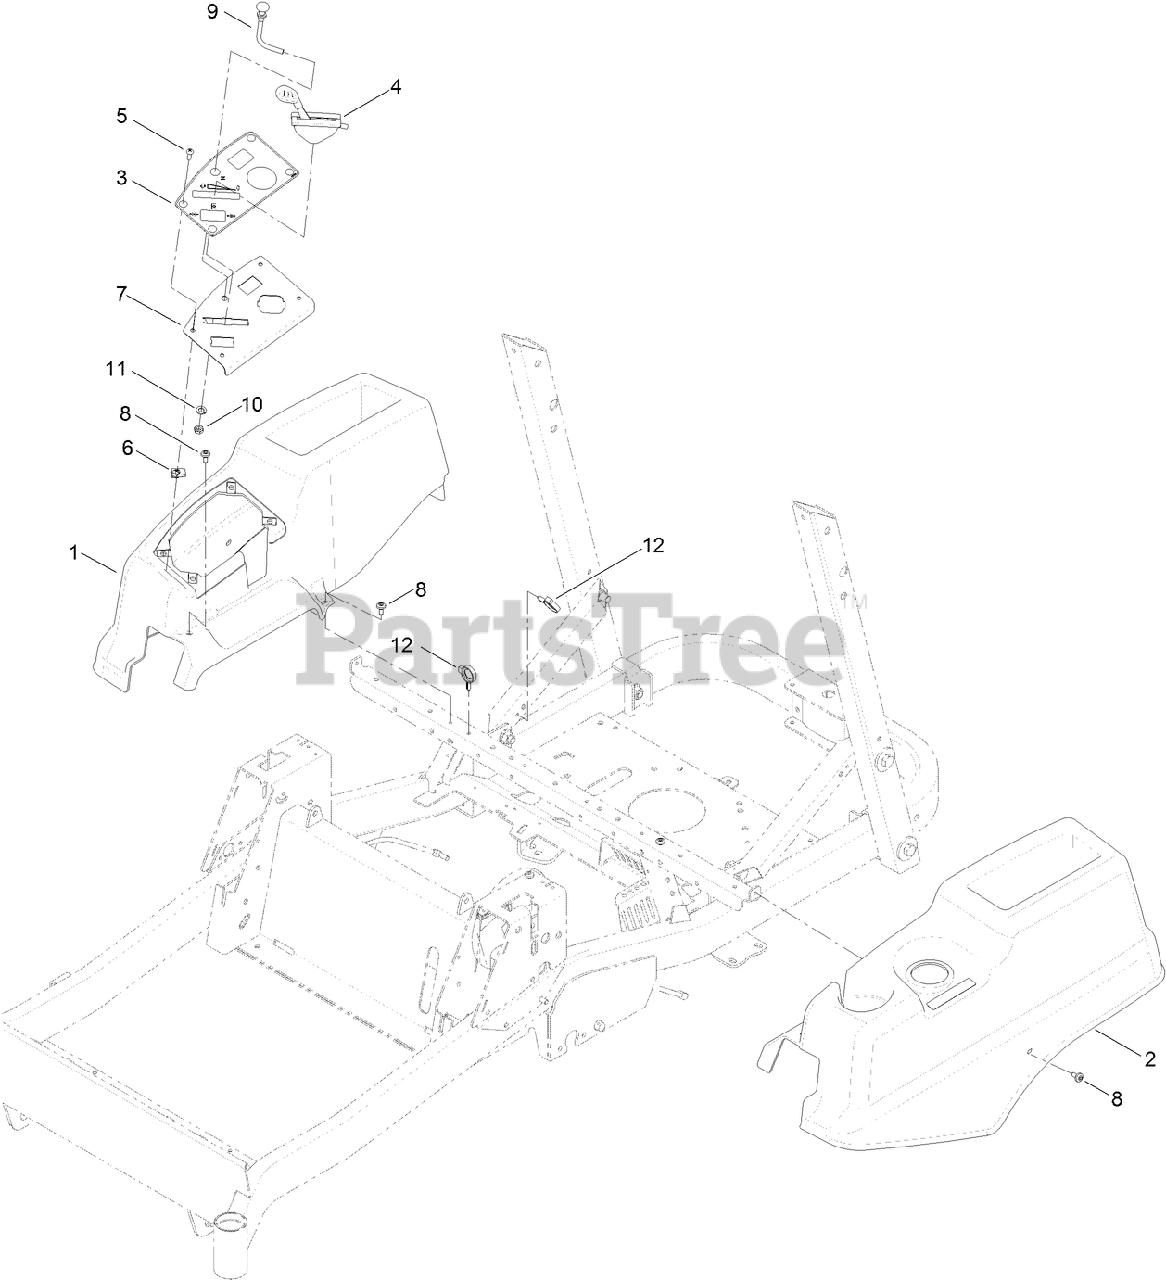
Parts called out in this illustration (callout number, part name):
1	POD-RH
2	POD-LH
3	DECAL-PANEL, CONTROL
4	CABLE-THROTTLE
5	SCREW-PRH
7	PANEL-CONTROL
8	SCREW-SHOULDER
9	CABLE-CHOKE
10	WASHER-LOCK
11	NUT-HJ
12	CLAMP-HOSE
